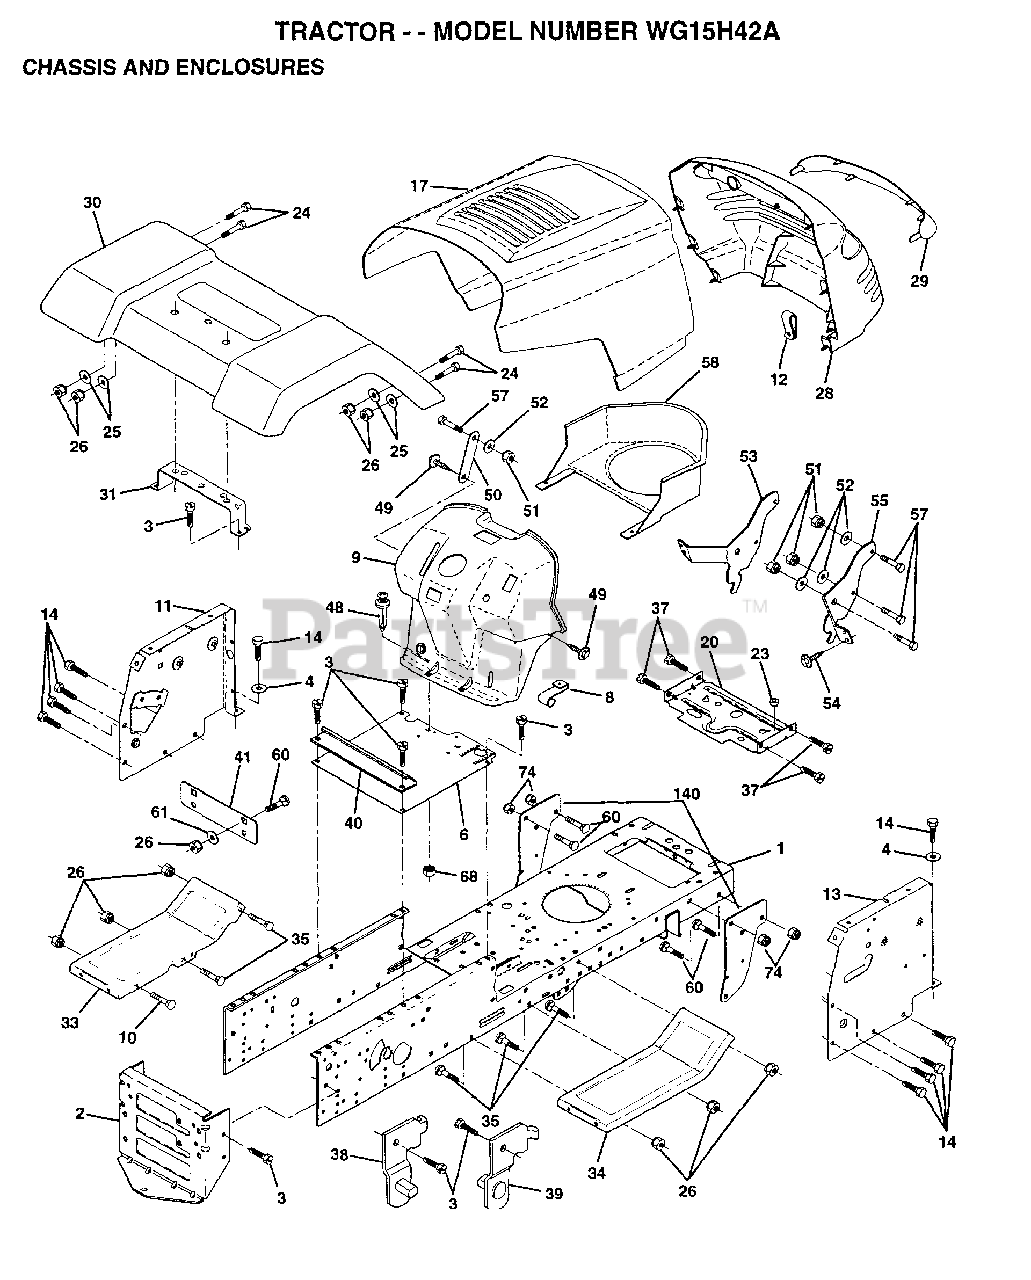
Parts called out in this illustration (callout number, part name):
1	CHASSIS WLDMT 11G
3	SCREW
4	WASHER
8	"CLIP,INSULATOR"
11	PANEL.DASH.LH.
12	CLIP.TINNERMAN
14	SCREW LT
20	PLATE.MTG.BTRY.TK
24	BOLT
25	WASHER
26	NUT
28	GRILL.P/L.EURO.
29	LENS.P/L.EURO.
31	BRACKET SUPT FEND
33	FOOTREST.LH.LT/GT
34	FOOTREST.RH.LT/GT
35	BOLT
37	SCREW LT
38	BRACKET ASM LH
39	BRACKET ASM RH
40	SPACER FENDER LT
41	PLATE EXTEN FEND
48	RIVET.PUSH.PLATE
49	SCREW HEX CRT
50	BRACE SUPT DASH
51	NUT
52	WASHER
53	BRACKET.GRILLE.LH
55	BRACKET.GRILLE.RH
58	AIR DUCT
60	BOLT
61	WASHER
68	NUT
